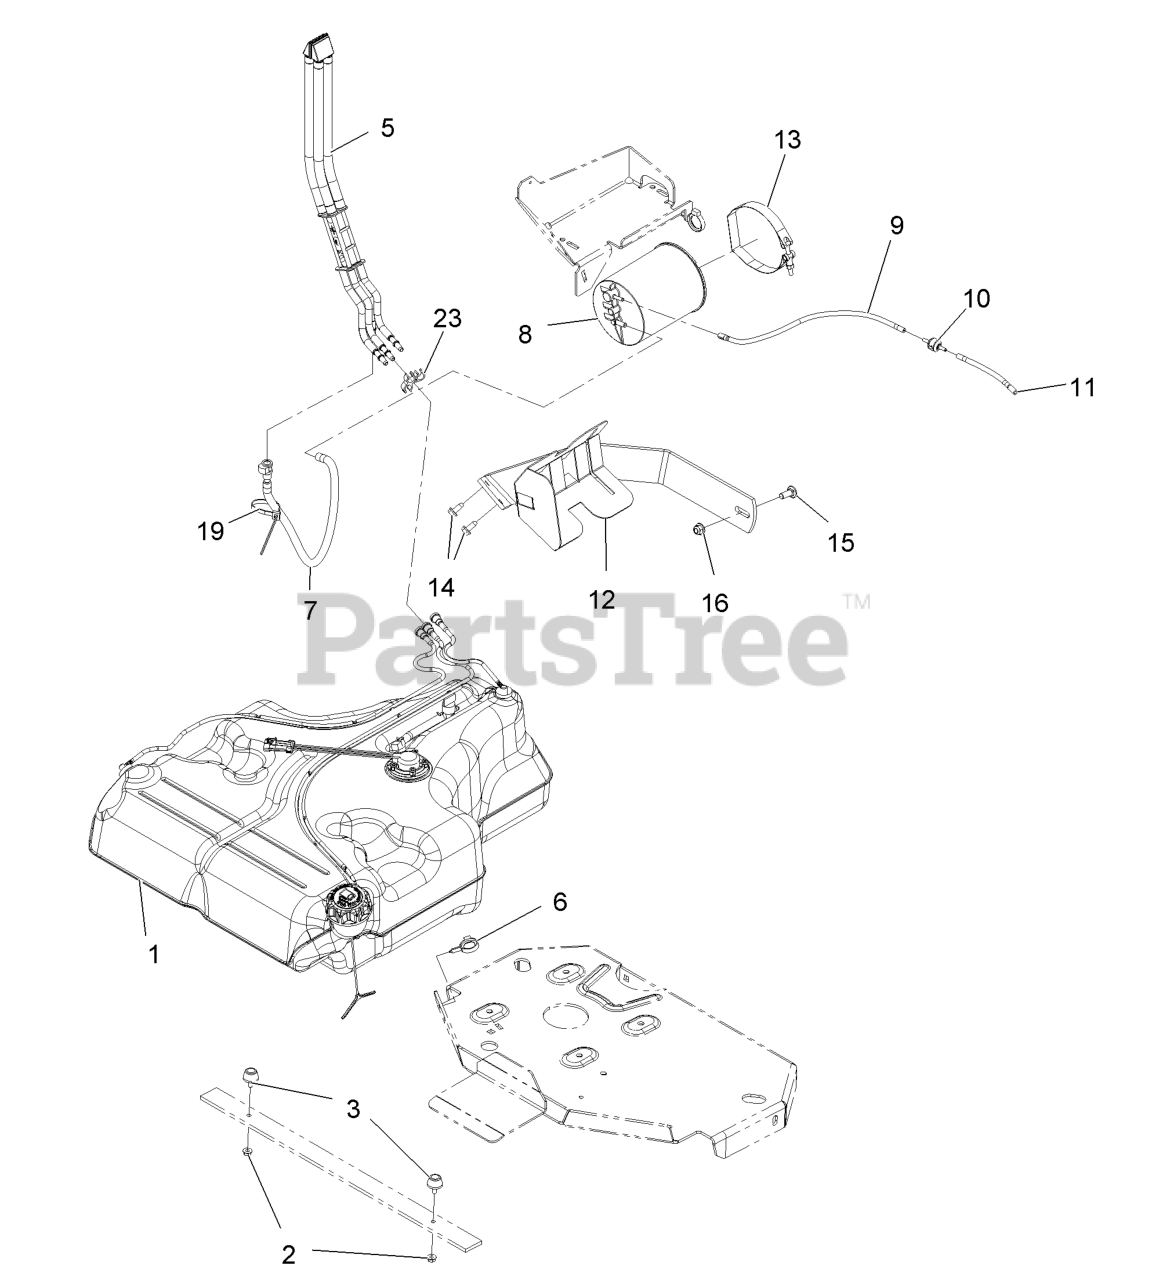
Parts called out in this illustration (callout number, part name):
3	BUMPER-RUBBER
5	FUEL MANIFOLD VENT ASM
6	CLAMP-HOSE
7	VENT HOSE ASM
8	CANISTER-CARBON, 1200CC
9	HOSE-VENT, FORMED
11	HOSE-VENT, FORMED
12	MOUNT-CANISTER
13	CLAMP, T-BOLT
14	Screw-HWH 5/16-18 X 3/4 Tf
15	SCREW-CARR
16	NUT-HF, NI
19	TIE-PLASTIC
23	CLIP-SPACER
